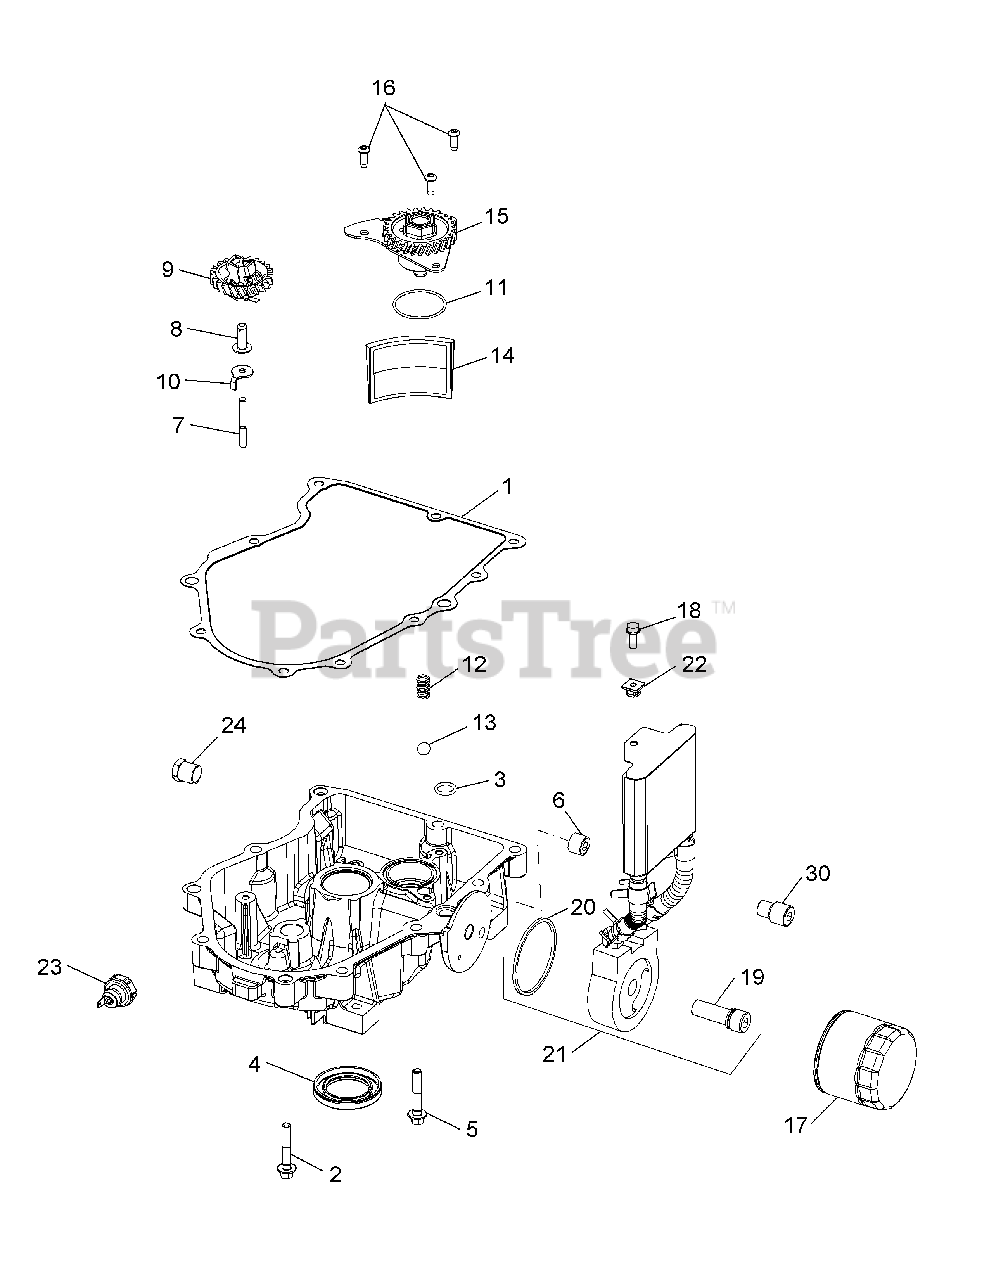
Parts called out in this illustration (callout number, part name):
1	Oil Pan Gasket
2	Flange Screw, M8 x 1.25 x .45
6	Countersink Pipe Plug, 3/8
7	Governor Gear Shaft
8	Governor Regulating Pin
9	Governor Gear Kit w/Pin
11	O-Ring (1.78" Dia.)
12	Compression Spring
13	Pressure Relief Ball
15	Oil Pump Assembly
16	Button Head Screw
18	Tap Screw, M6 x 1.7 x 18
19	Oil Filter Nipple
20	Oil Cooler O-Ring
21	Oil Cooler Kit (Inc. 19 & 20)
22	Plastic Nut (Black)
23	Oil Pressure Switch
24	Pipe Plug, 3/8
